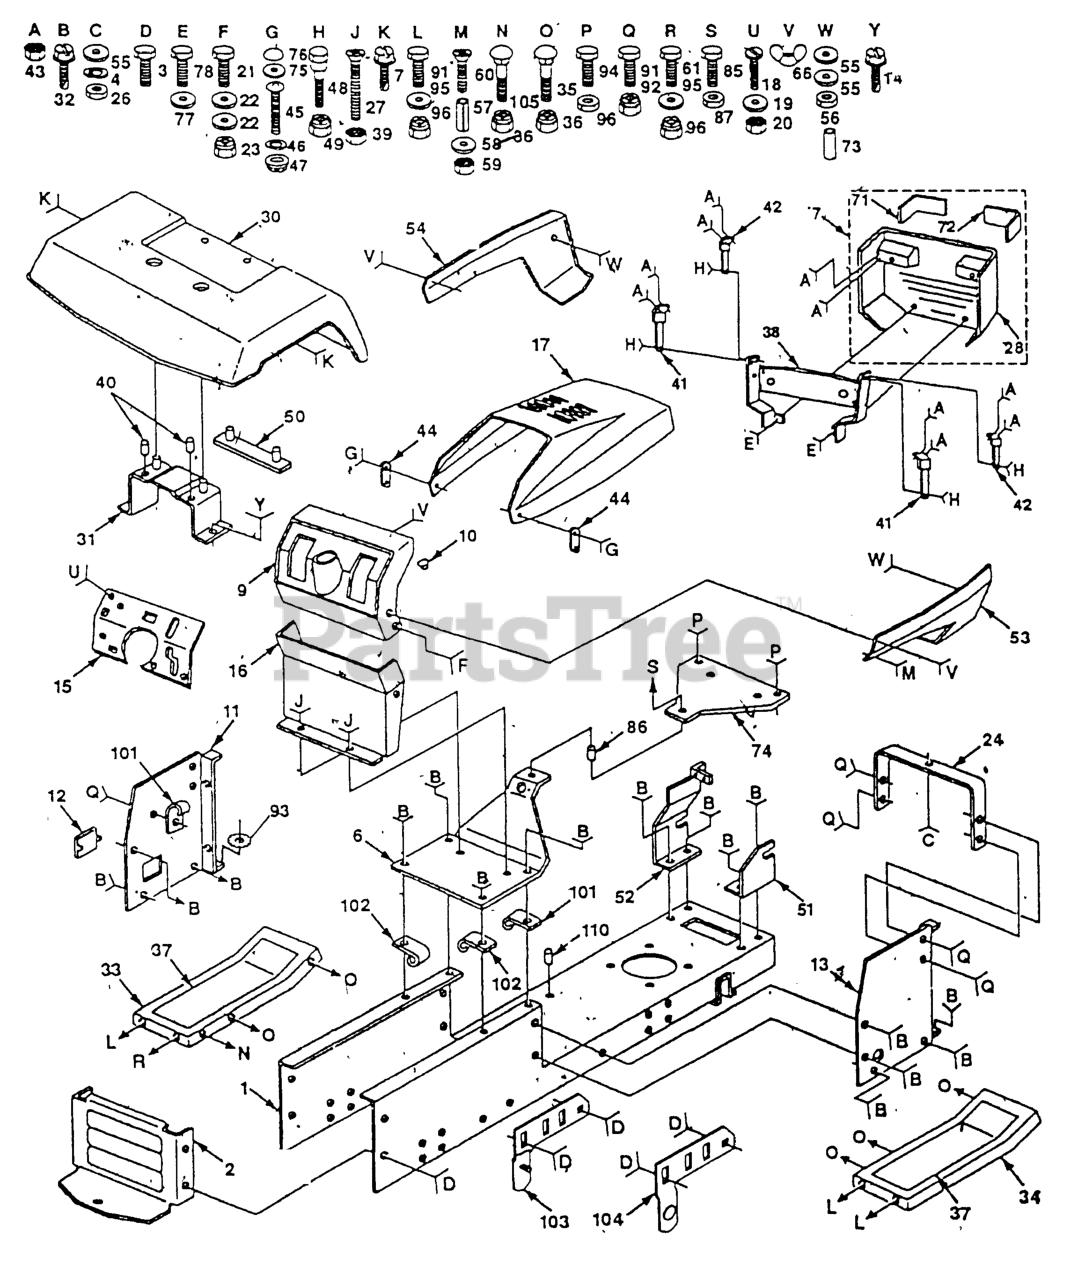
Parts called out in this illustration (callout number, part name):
1	CHASSIS
2	STRETCH DRAWBAR
3	SCREW
4	LOCKWASHER
7	SCREW LT
8	Washer Lock Hvy Helical 1/4
10	PLUG-DASH T
11	PANEL DASH LH
12	COVER ACCESS
13	PANEL DASH RH
14	SCREW
15	DASH PLATE
16	DASH LOWER YT NLA
17	HOOD
18	Screw Mach Trhd 5/16 - 18 UNC x 3/4
19	WASHER
20	NUT
21	BOLT
22	WASHER
23	NUT
24	SUPPORT ASS'Y
25	Washer Lock Ext. Tooth 1/4
26	NUT
27	Screw mach Trhd 5/16 - 18 UNC x 3/4
28	GRILL COMPLETE
31	FENDER BRKT
32	SCREW
33	ROLL PIN NLA
34	PAD,SPACER
35	BOLT
36	NUT
37	PAD FOOTREST T
38	SUPPORT ASS'Y
39	NUT
40	NUT-PUSH YT
41	STRAP ASSY LT
42	STRAP ASSY LT
43	NUT
44	LATCH.HOOD.
45	SCREW
46	LOCKWASHER #10
47	WELDNUT
48	BOLT T
49	NUT.CROWNLOCK.1/4
50	STRAP
51	SUPPORT LH YTH
52	SUPPORT RH YTH
53	SIDE PANEL ASSY LH
54	SIDE PANEL ASSY RH
55	WASHER PM
56	NUT
59	NUT **
60	RP SCREW
66	WING NUT
71	LENS LH
72	LENS RH
73	SPACER NLA
74	PLATE, BATTERY
75	SNAP CAP LT
77	WASHER PM
85	Bolt Fin Hex 5/16 - 18 Unc x 2 Gr. 2
87	NUT.71038.31-18.HEX.NYLOCK
88	BOLT.FIN.HEX.5/16-18X3/4
89	LOCKNUT
91	BOLT
92	NUT
93	LOCKWASHER
94	BOLT
95	WASHER
96	NUT
101	CLIP,INSULATOR
103	BRACKET LH PIVOT
104	BRACKET RH PIVOT
105	BOLT D
110	SNAP BUSHING T
